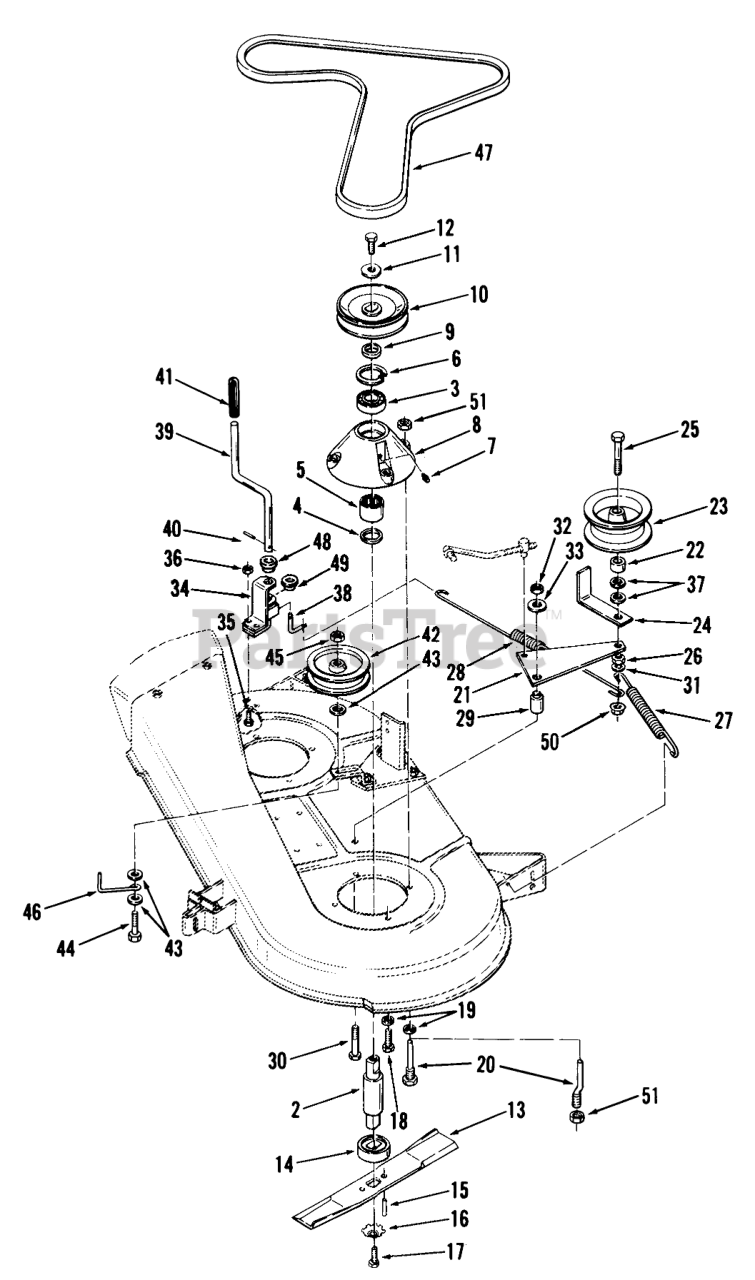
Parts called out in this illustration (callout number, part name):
1	Spindle Assembly (includes parts 2, 3, 4, 5, 6, 7, & 8)
2	SPINDLE MOWER
3	BEARING-BALL
4	OIL SEAL
5	BEARING-NEEDLE
6	INT SNAP RING
7	Fitting-Grease
8	HOUSING
9	SPACER
10	PULLEY-BLADE
11	WASHER
12	Bolt
13	S/A BLADE KIT
14	Spindle Cup
15	SPIROL ROLL PIN
16	WASHER
17	Bolt
18	Bolt
19	LOCKWASHER
20	GUIDE-BELT
21	ARM-IDLER
22	SPACER
23	PULLEY-IDLER
24	Belt Guide
25	Bolt 3/8-16 x 3 1/4
26	Nut
27	SPRING
28	SPRING-ENGAGEMENT
29	BUSHING-BRAKE PIVOT
30	Bolt
31	Washer
32	Nut
33	WASHER
34	PIVOT BRKT ASM OBS
35	Bolt
36	Nut
37	Washer
38	Engagement Bar
39	Engagement Lever
40	Pin-Roll
41	GRIP
42	Idler Pulley
43	Washer
44	Bolt
45	Nut
46	GUIDE-BELT
47	V-BELT
48	NYLINER BUSHING
49	BUSHING-NYLINER
50	LOCKNUT-FLANGE
51	Nut
